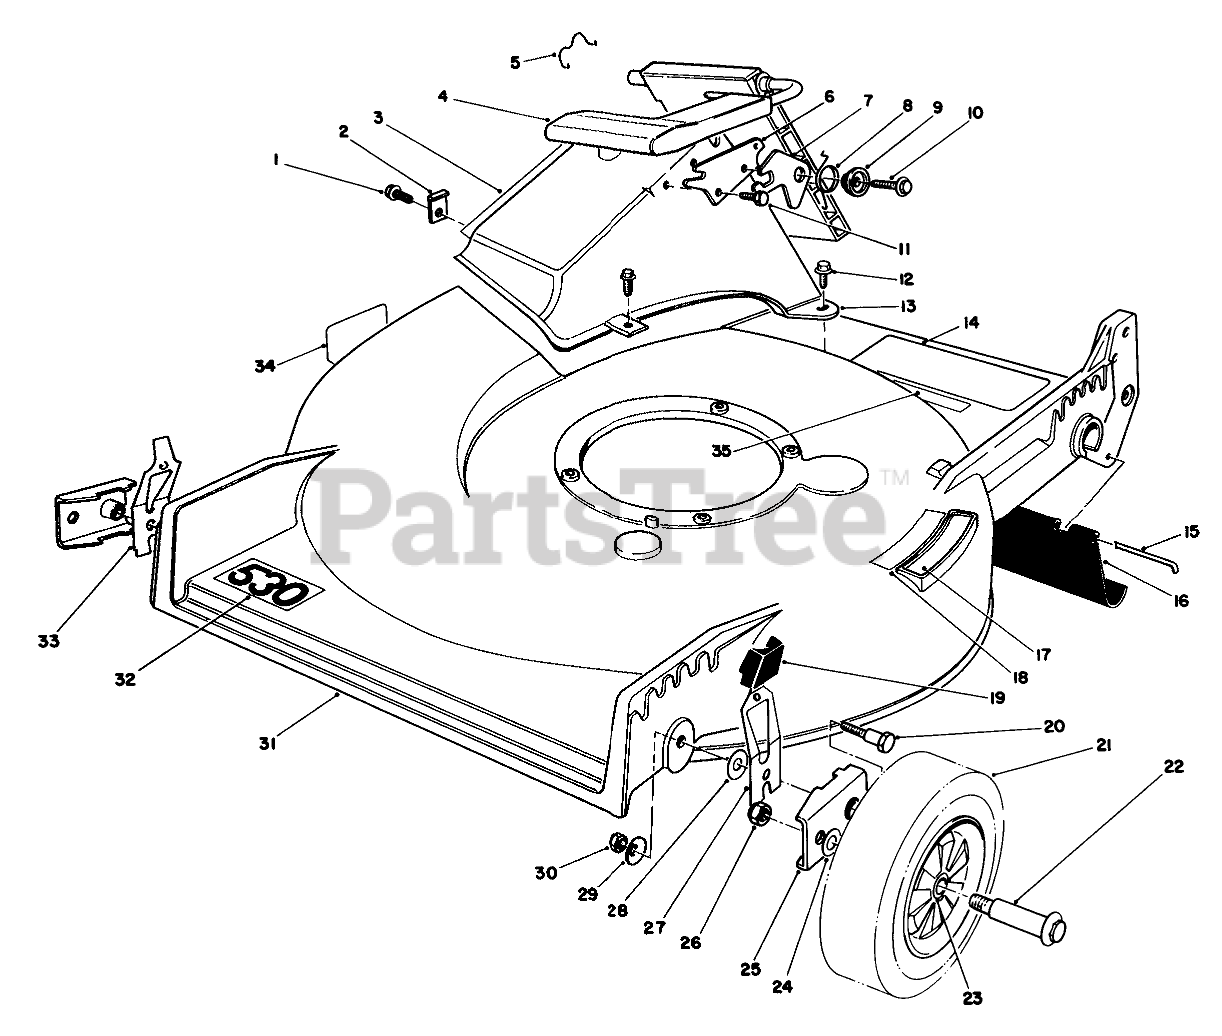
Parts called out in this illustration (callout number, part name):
1	SCREW
2	TUNNEL CLIP
3	Decal-Attention
4	Discharge Door Assembly
5	DOOR RET SPRING
6	DOOR LATCH PLATE
7	SAFETY LATCH
8	TORSION SPRING
9	DOOR SPACER
10	SCREW-HWH
11	SCREW-PLASTITE
12	SCREW-HWH
13	Tunnel Discharge
14	Danger-Decal
15	Rod Shield
16	SHIELD - TRAILING
17	STEP PAD DECAL
18	Decal-Place Foot Here
19	KNOB-ARM
20	PIVOT SCREW
21	Wheel & Tire Assembly (Incl. Ref. #23)
22	BOLT-WHEEL
23	BUSHING
24	WASHER
25	HP PIVOT ARM ASM
26	Nut
27	L. HP SPRING ARM ASM
28	WASHER-PIVOT
29	WASHER-BELLEVILLE
30	NUT-LOCK, NI
31	21HP RB-SUZ HSG/DECAL
32	Decal-530
33	R HP SPRING ARM ASM
34	DECAL-DANGER
35	Decal
